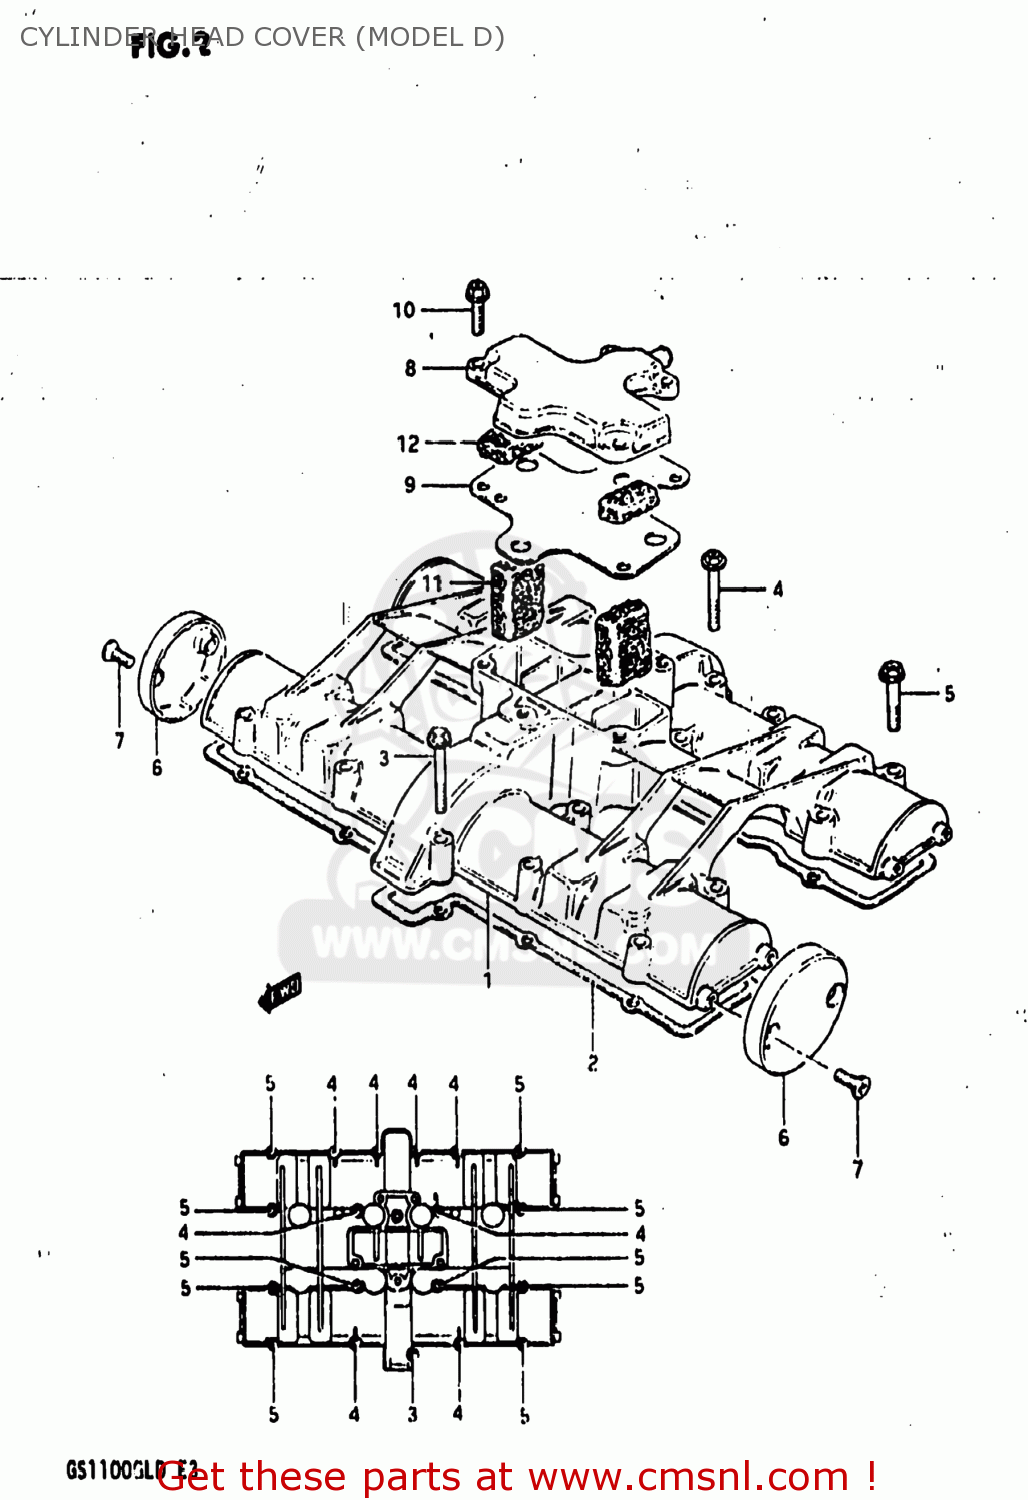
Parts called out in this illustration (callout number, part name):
1	COVER,CYLINDER HEAD
2	GASKET,CYLINDER HEAD COVER (MCA)
3	BOLT (6X45)
4	BOLT (6X40)
5	BOLT
6	CAP,CYLINDER HEAD COVER
7	SCREW(5X12)
8	COVER,BREATHER
9	GASKET (MCA)
10	BOLT
11	COVER,BREATHER
12	SEPARATOR,OIL BREATHER
